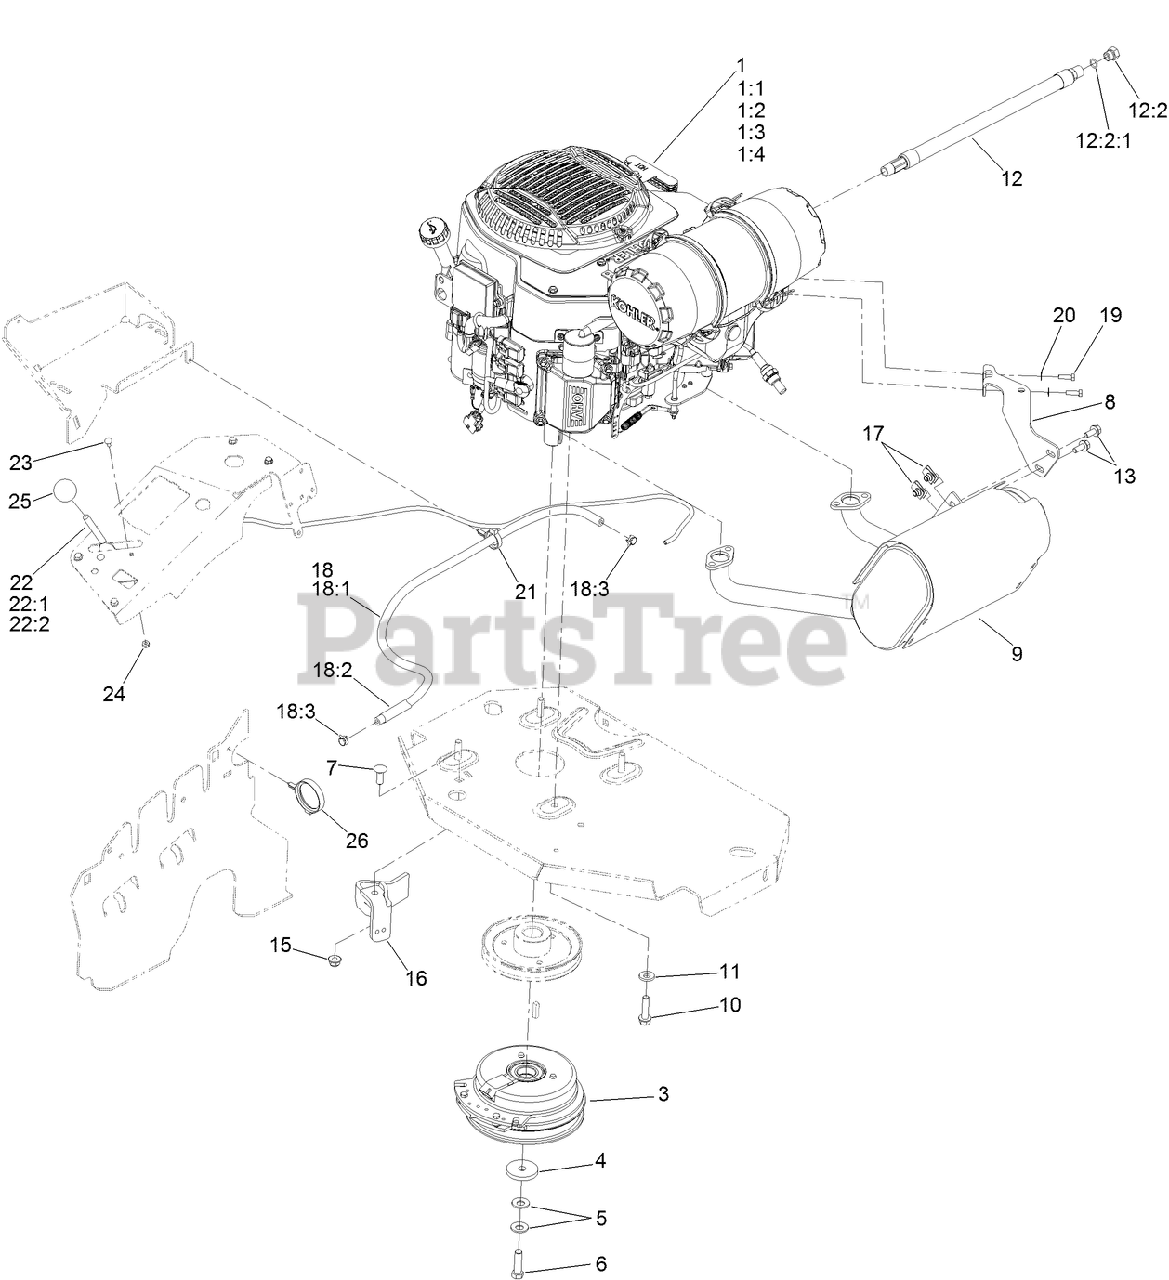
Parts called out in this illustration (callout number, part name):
1:1	KOHLER 52 050 02-S ENGINE OIL FILTER
1:2	KOHLER 25 083 01-S ENGINE AIR FILTER
1:3	KOHLER 25 083 04-S SAFETY FILTER
1:4	KOHLER 25 050 42-S FUEL FILTER
3	CLUTCH KIT
4	WASHER-CLUTCH
5	WASHER-SPRING
6	SCREW-HH, W/LOCTITE
7	SCREW-CARR
8	MUFFLER BRACKET KIT
9	MUFFLER KIT
10	SCREW-HWH
11	WASHER-BELLEVILLE
12	OIL DRAIN HOSE ASM
12:2	PLUG-HH
12:2:1	O-RING
13	SCREW-HH
15	NUT-HF, NI
16	CLUTCH-ANCHOR
17	NUT-U
18	FUEL LINE ASM
18:1	HOSE-FUEL
18:2	SLEEVE-THERMAL
18:3	CLAMP-HOSE
19	SCREW-HH
20	WASHER-SPRING
21	CLAMP-HOSE
22	THROTTLE CONTROL ASM
22:1	LEVER-THROTTLE
23	BOLT-CARR
24	NUT-LOCK, NI
25	KNOB-BALL
26	CLAMP-HARNESS
